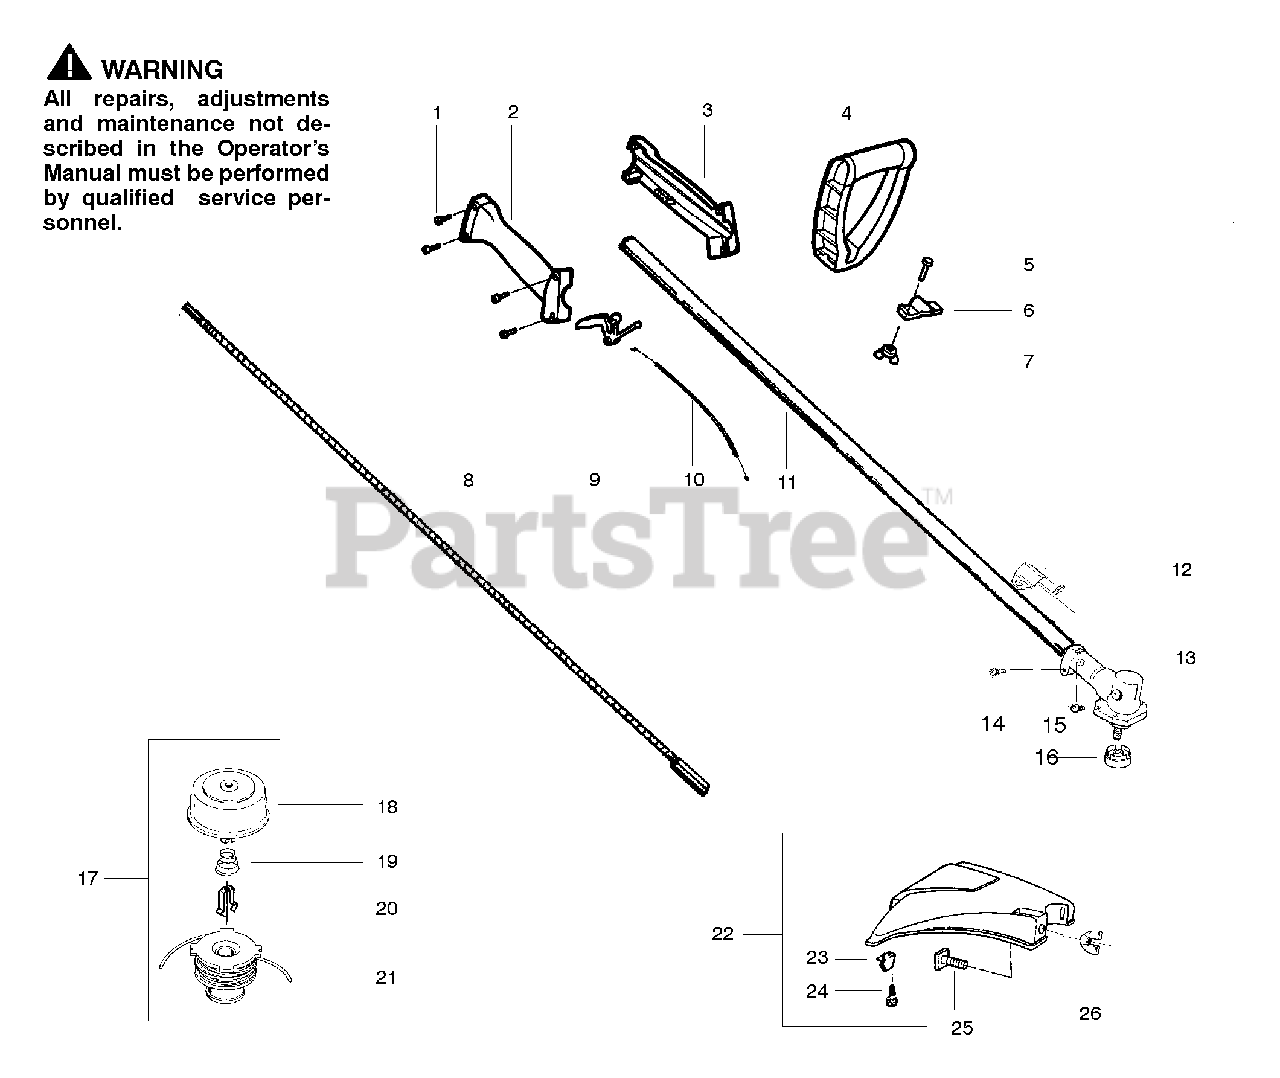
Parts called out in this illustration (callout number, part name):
1	Screw-Throttle Hsg.
2	Throttle Hsg. (Right)
3	Throttle Hsg. (Left)
4	Assist Handle
6	Clamp-Handle
7	Wingnut
8	Shaft- Flex-52"
10	Throttle Cable Ass'y.
11	Assy-Drive Shaft
13	Kit-Gear Box Assy.
16	Dust Cup
17	Cutting Head Ass'y.
18	Hub Ass'y.
19	Spring-Return
20	Retainer-Spool
21	Spool w/Line
22	Kit-Shield Assy.
23	Line Limiter
24	Screw-Line Limiter
26	Wingnut
